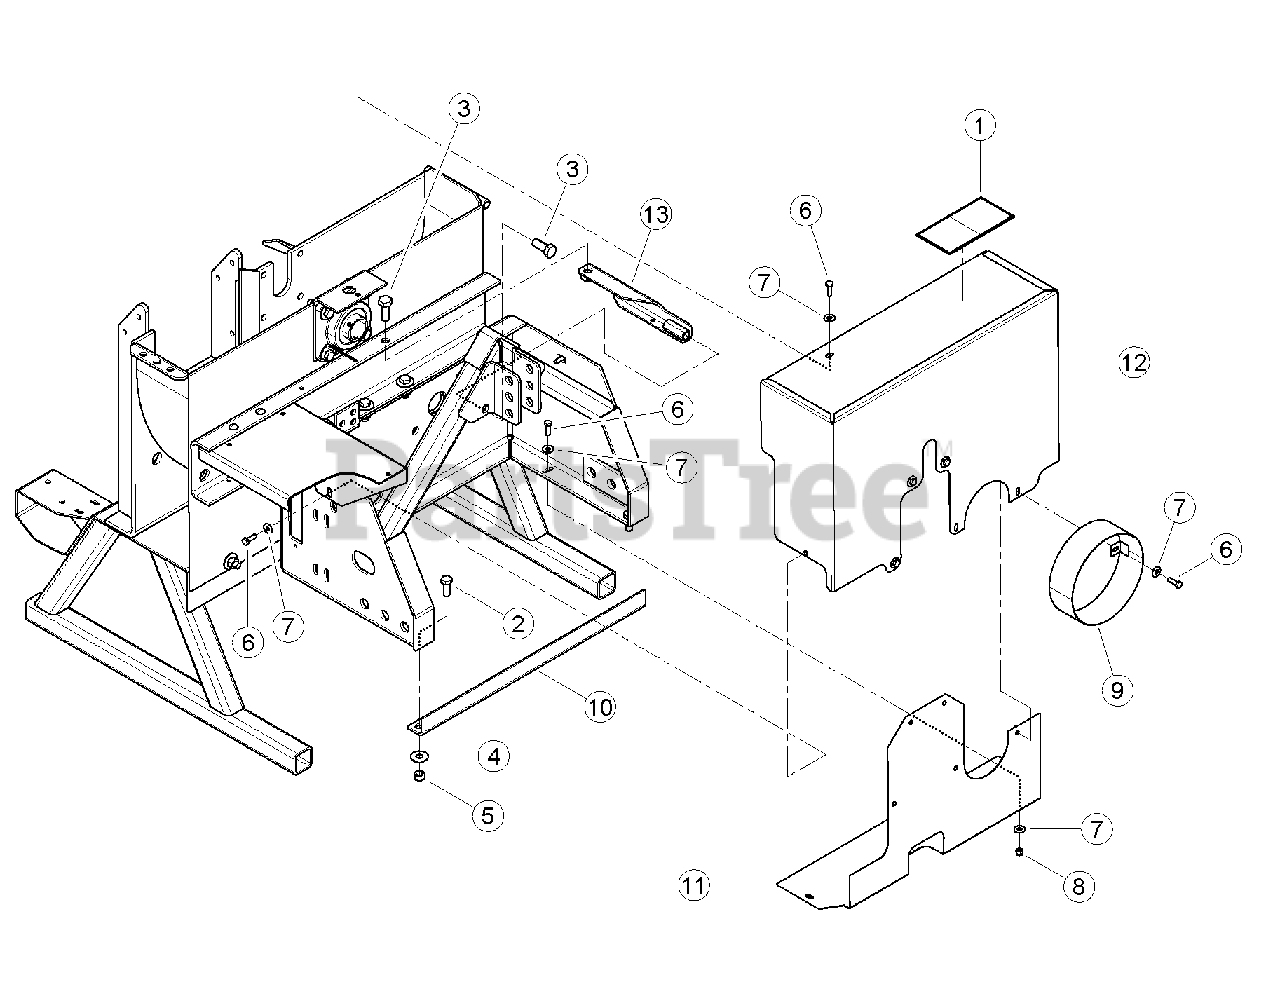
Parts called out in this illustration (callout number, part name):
1	DECAL, PTO DANGER ISO
2	BOLT, 1/2 X 1-1/4 HEX HD GR5 NC ZP
3	BOLT, 5/8 X 1-1/2 HEX HD GR5 ZP
4	WASHER, 1/2 FLAT ZP
5	NUT, 1/2 CENTERLOCK GRB ZP
6	BOLT, 5/16 X 1 HEX HD GR5 NC ZP
7	WASHER, 5/16 FLAT ZP
8	NUT, 5/16 NE NYLOCK ZP
9	WELDMENT, JOINT SHIELD
10	BRACE, 3 POINT BOTTOM
11	WELDMENT, GUARD PTO LOWER BELT
12	WELDMENT, GUARD PTO UPPER BELT
13	WELDMENT, BRACE PTO 3-POINT
